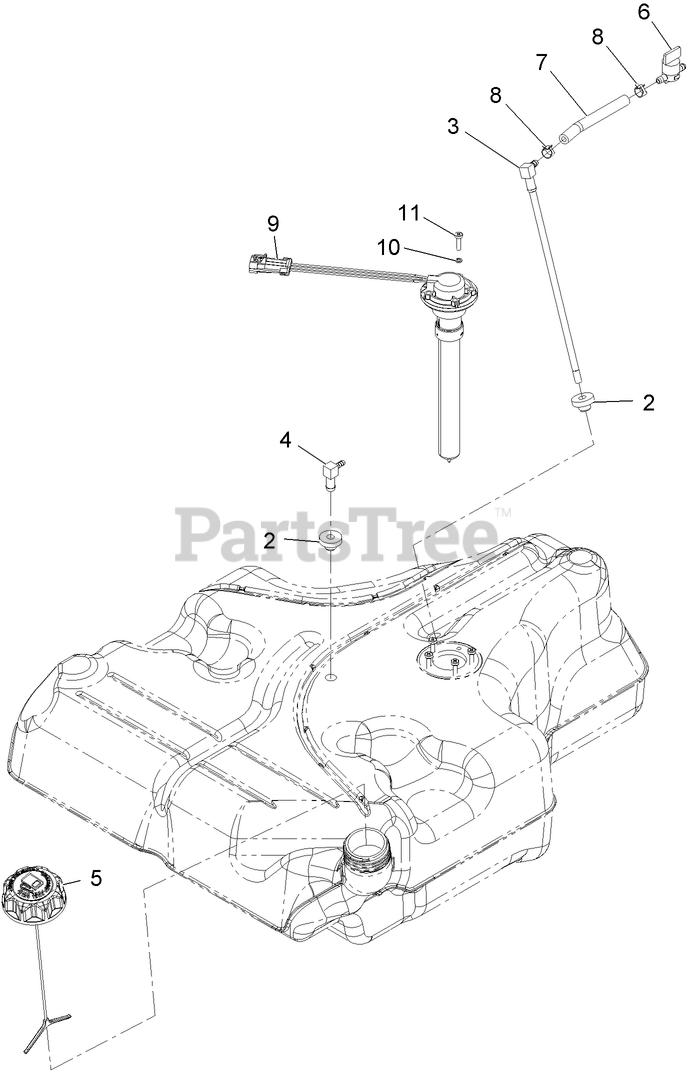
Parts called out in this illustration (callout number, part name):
2	BUSHING
3	FUEL LINE KIT (WITH GROMMET)
4	FITTING-ELBOW, 90 DEG
5	CAP-FUEL, RATCHETING
6	VALVE-FUEL
7	HOSE-FUEL
8	CLAMP-HOSE
9	SENDER-FUEL
10	WASHER-LOCK
11	SCREW-PAN
